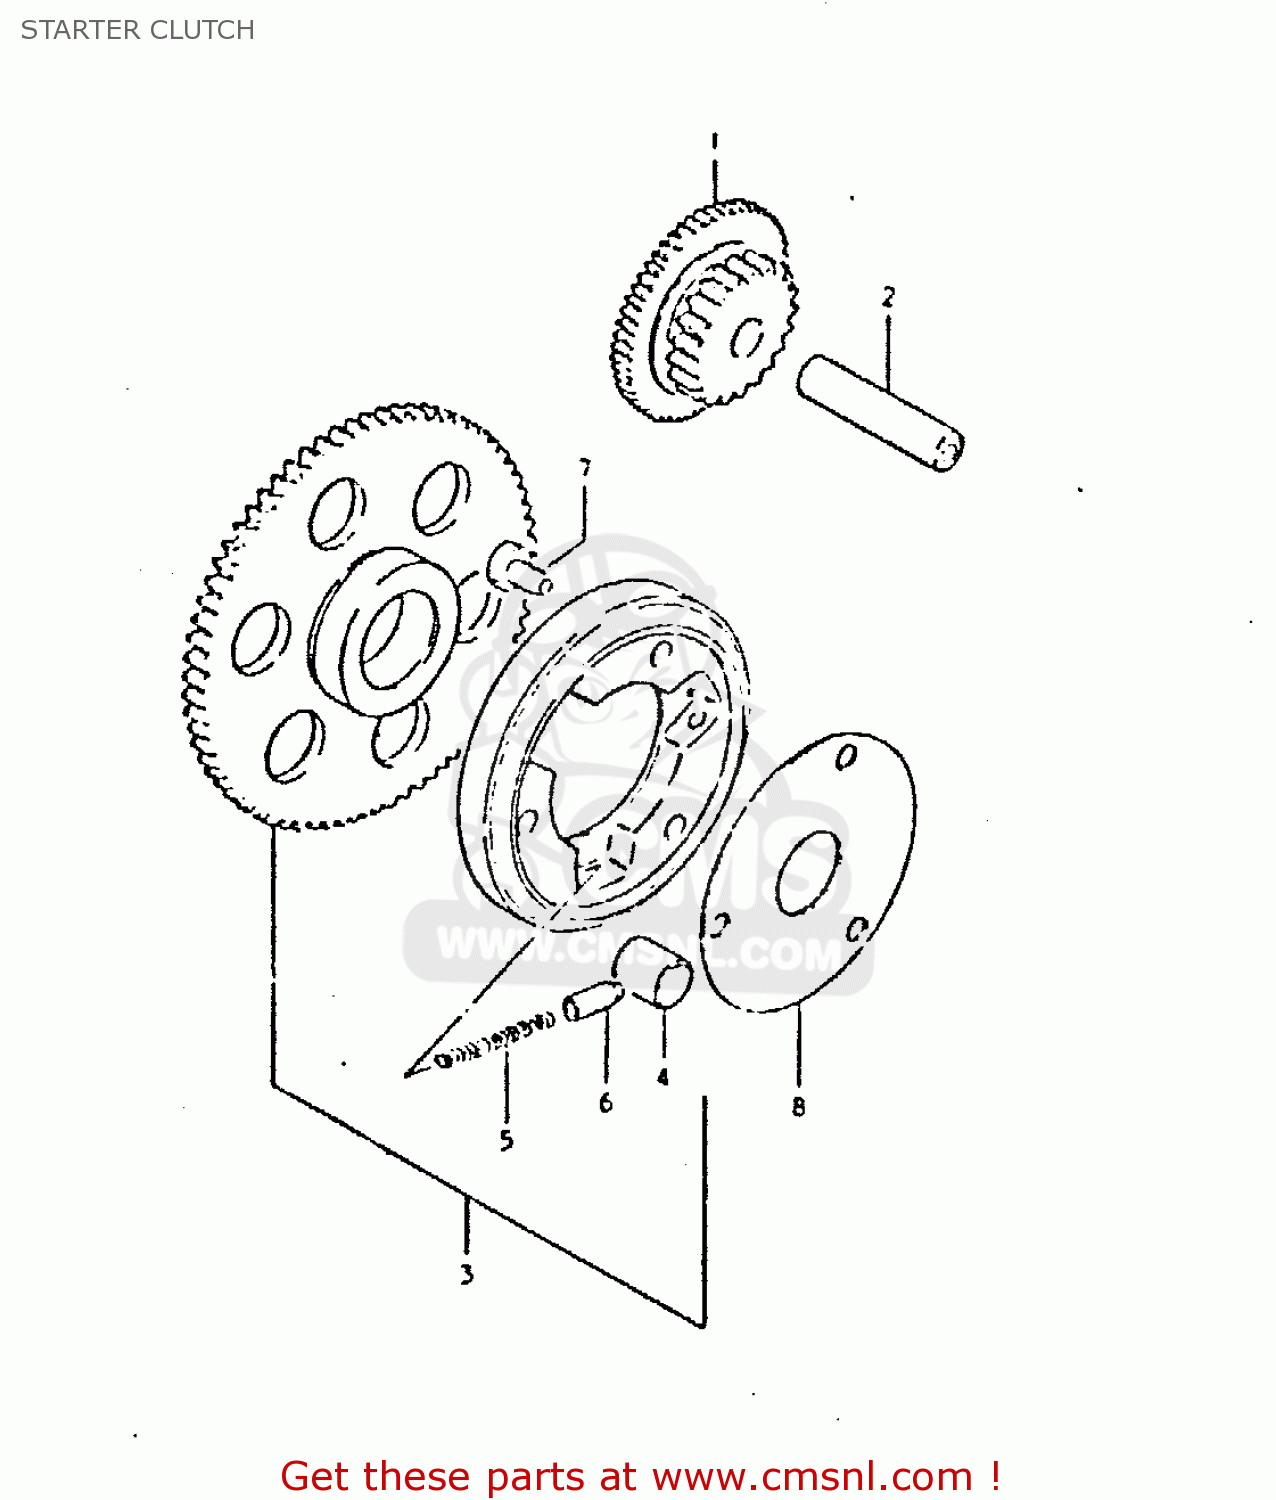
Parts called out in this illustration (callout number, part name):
1	GEAR,STARTER IDLE
2	PIN(7.4X13X56)
3	CLUTCH SET,STARTER
4	ROLLER(15X13)
5	SPRING
6	PIECE,PUSH
7	BOLT
8	SHIM,STARTER CLUTCH HUB
